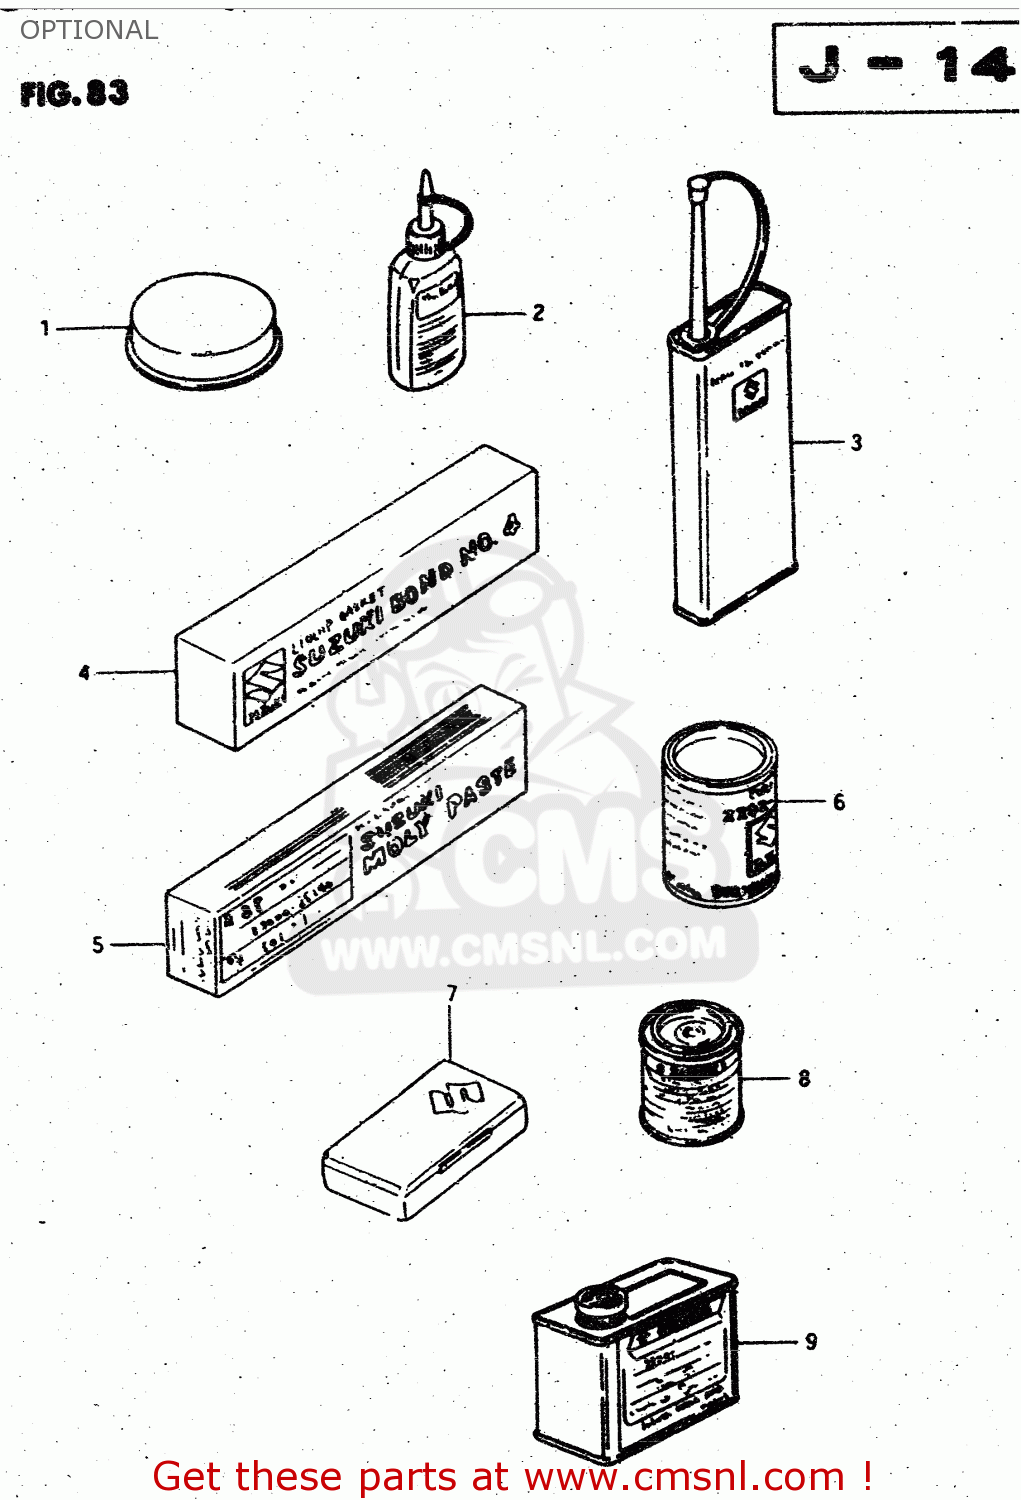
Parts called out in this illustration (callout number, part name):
1	GREASE,PBC FOR BRK PAD 20G
2	THREAD LOCK NO.1342
3	THREAD LOCK NO.1401 CLEAR 200G
4	LIQUID GSKT NO.1207B 100G BLK
5	SUZUKI MOLY PASTE
6	GREASE(C)EP2 LITHIUM 150G
7	TUBE REPARING TOOL
8	PAINT,BLACK
9	PAINT (BLACK)
